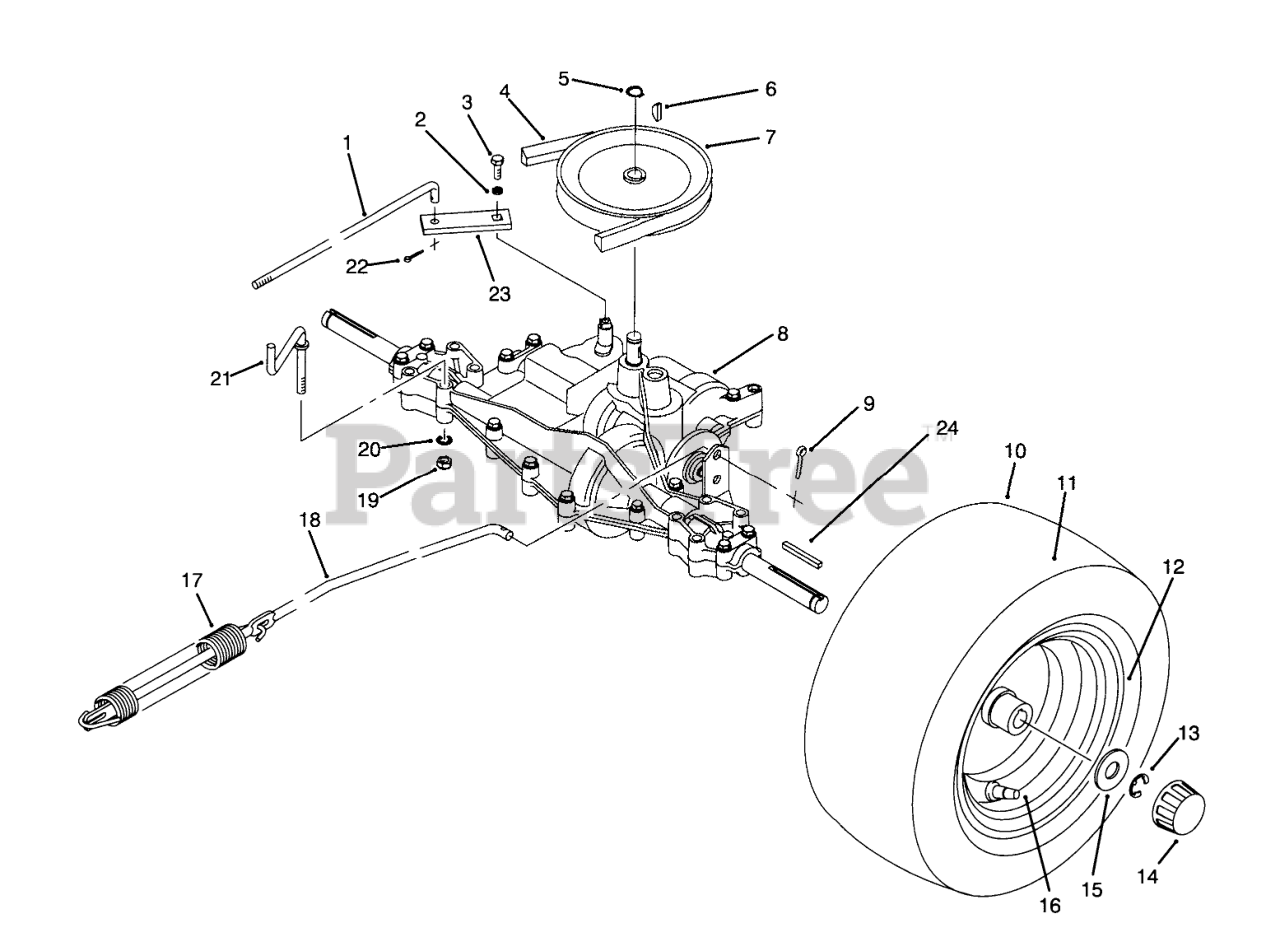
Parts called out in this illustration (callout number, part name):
1	LINK-SHIFT
2	WASHER-LOCK
3	SCREW-HH
4	V-BELT, TRACTION
5	RING-SNAP, EXTERNAL
6	KEY-WOODRUFF
7	PULLEY-TRANSAXLE
8	TRANSAXLE 915-019
9	PIN-COTTER
11	TUBE-INNER
12	REAR WHEEL ASM
13	E-RING
14	CAP-HUB
15	WASHER-PLAIN
16	STEM-VALVE
17	SPRING-EXT
18	ROD-BRAKE
19	NUT-LOCK, NI
20	WASHER-LOCK, INTERNAL
21	GUIDE-LOWER BELT
22	PIN-COTTER
23	LINKAGE
24	KEY-SQUARE
